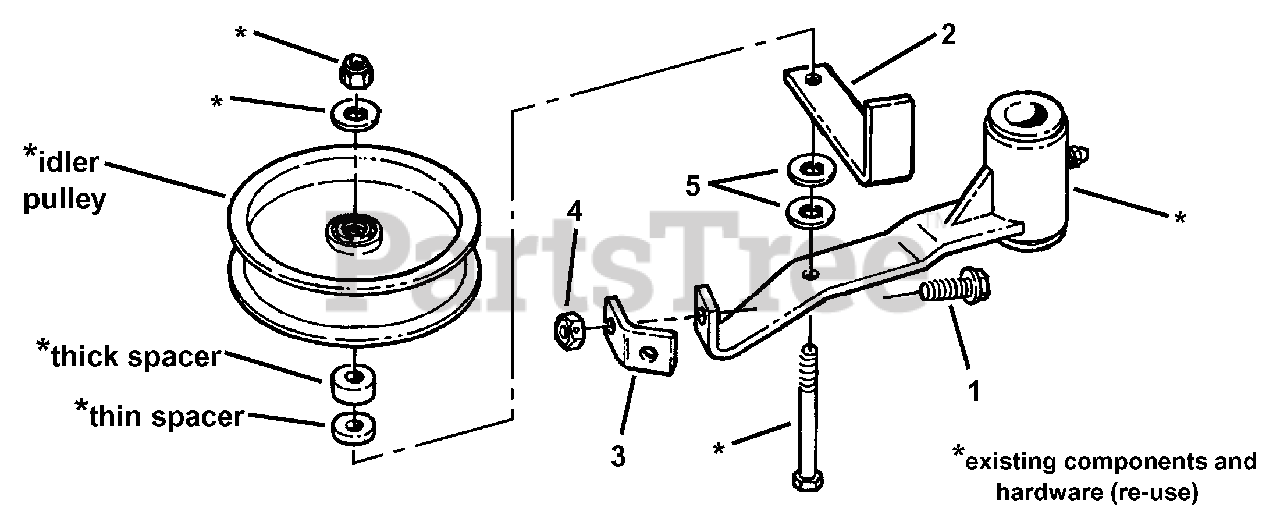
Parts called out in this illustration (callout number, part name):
1	BOLT, 3/8-16 x 1" Hex Flange Lock, Grade 5
2	RETAINER, Belt
3	BRACKET, Idler
4	NUT, 3/8-16 Hex Nyloc
5	WASHER, 3/8" Flat
